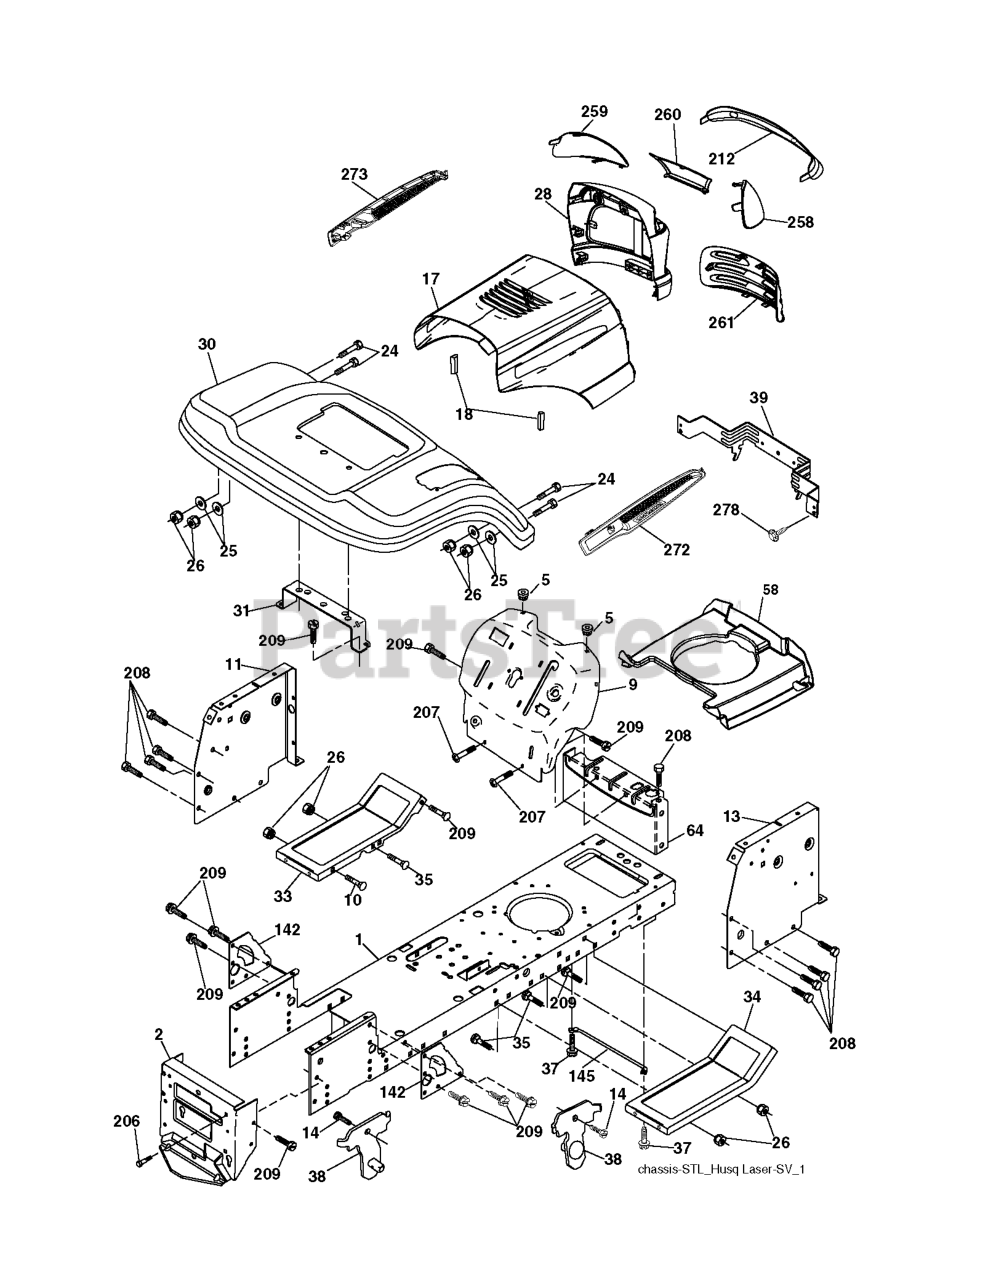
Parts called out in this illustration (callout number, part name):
1	CHASSIS STAMPING
2	DRAWBAR, 12GA
5	BUMPER.RUBBER.HOOD
9	DASH.STL.PLM.CAB.N/AMM.N/HM.05
10	BOLT D
11	PANEL.DASH.LH.LTX
17	VENT.HOOD.LASER.III
18	BUMPER.HOOD.LARGE.1.75"
25	WASHER
26	NUT
30	FENDER.PNT.LTST.W/S.N/C.422ROS
31	BRACKET FENDER
33	FOOTREST.LH.BLACK
34	FOOTREST.RH.BLACK
37	Screw 5/16-18 x 1/2 Hex, Self Tapping 5/16-18 x 1/2
38	BRACKET.ASM.PIVOT.MOWER.REAR
39	BRACKET PIVOT
64	DASH LOWER
142	PLATE REINFORCEMENT
145	ROD.PIVOT.HOOD
206	SHOULDER BOLT 5/16-18TT
207	SCREW, 5/16-18 X 1/2
208	SCREW 3/8-16X1/2
209	SCREW, 3/8-16X3/4
212	INSERT.LENS.REFLECTIVE
258	LENS LH
259	LENS LH
260	COVER.LENS.HUSQ.LASER
272	VENT.HOOD.LASER.
273	VENT.HOOD.LASER.
278	SCREW
